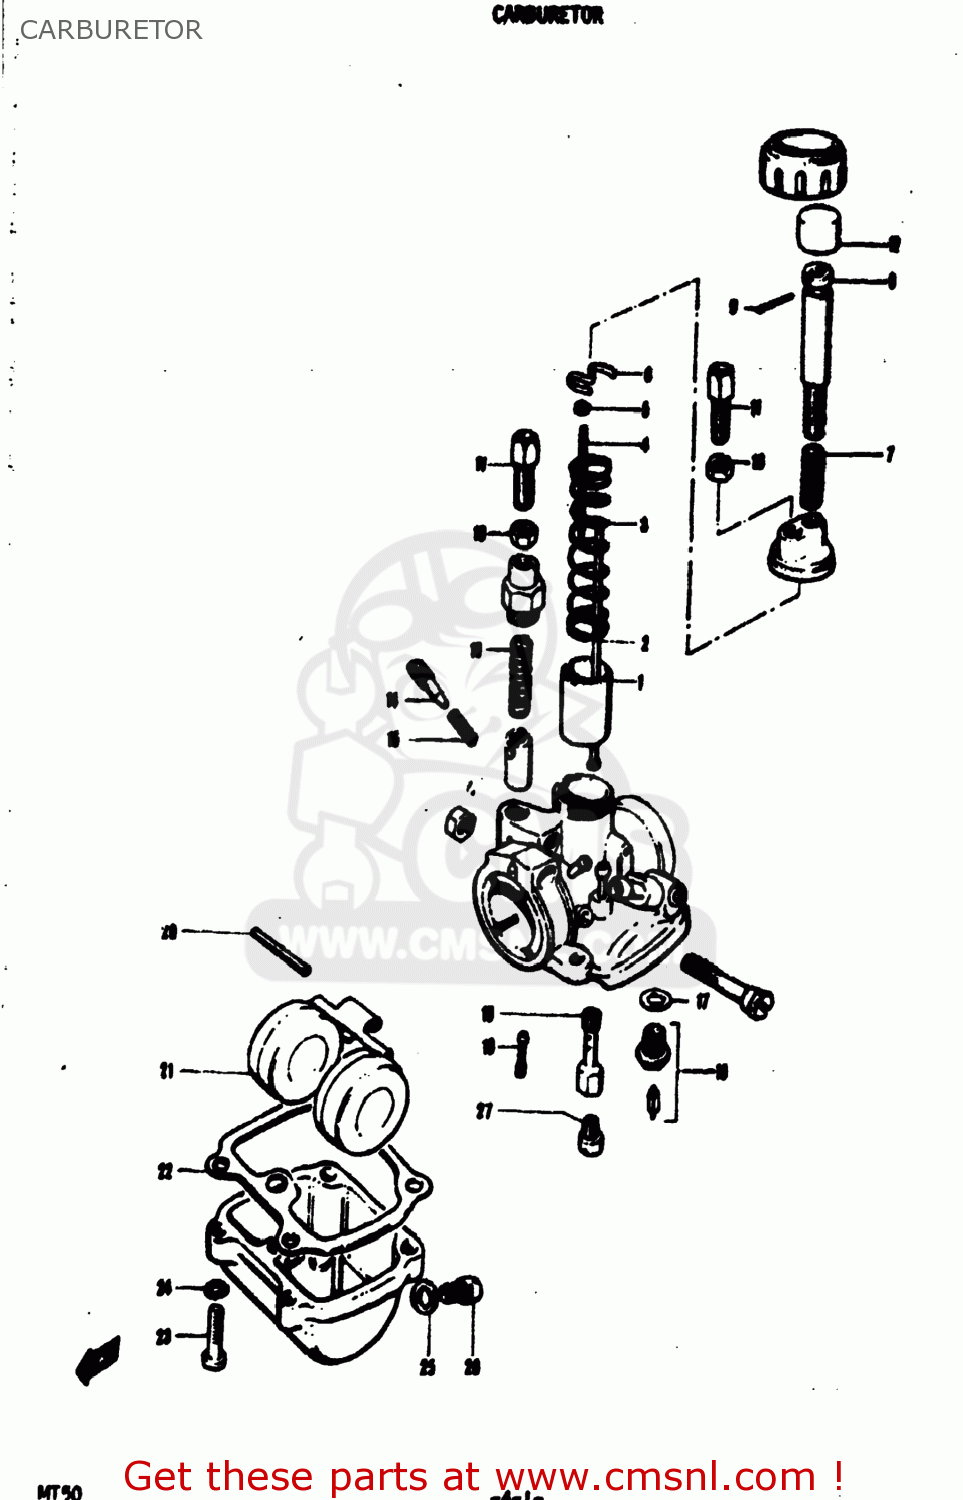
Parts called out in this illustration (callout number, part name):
1	VALVE,THROTTLE(CA:2.5)
2	ROD,THROTTLE VALVE STOP
3	SPRING,THROTTLE VALVE
4	NEEDLE JET
5	CLIP,NEEDLE
6	PLATE,THROTTLE VALVE
7	SPRING,THROTTLE STOP SCREW
8	SCREW,THROTTLE STOP
9	PIN 12X10
10	NUT
11	ADJUSTER,CABLE
12	CAP,THROTTLE VALVE STOP SCREW
13	SPRING
14	SCREW,PILOT AIR
15	SPRING
16	VALVE ASSEMBLY,NEEDLE
17	GASKET,NEEDLE VALVE (NAS)
18	JET,NEEDLE
19	JET
20	PIN,FLOAT
21	FLOAT
22	GASKET,FLOAT CHAMBER (NAS)
23	SCREW
24	LOCK WASHER
25	GASKET,DRAIN,PLUG (NAS)
26	PLUG
27	JET
